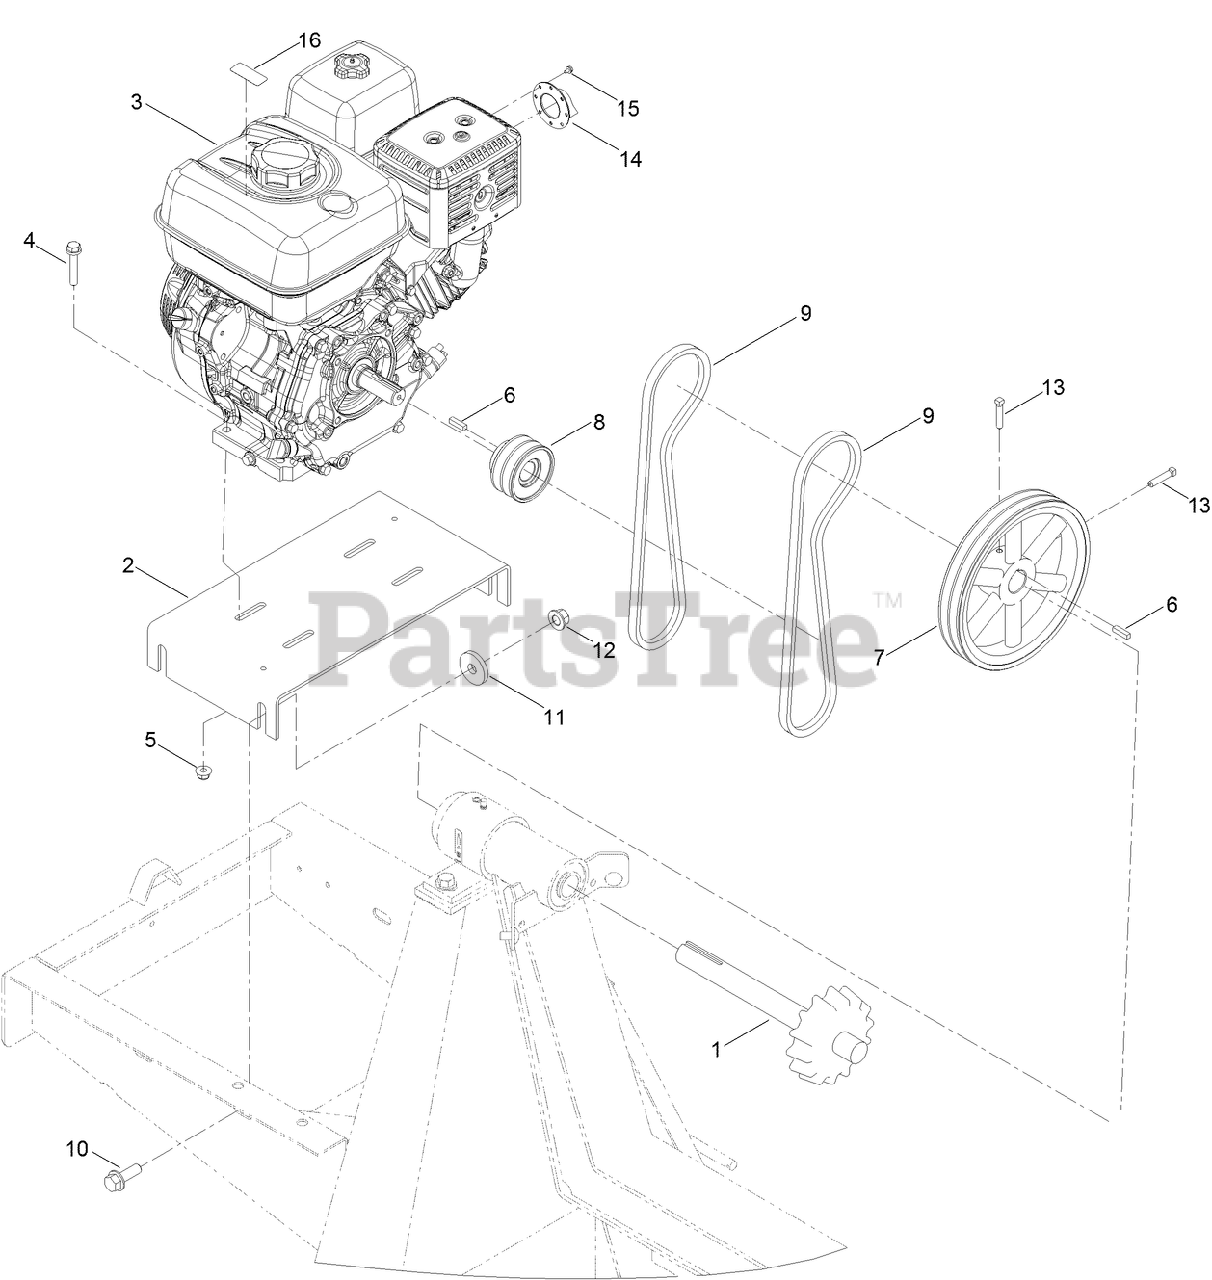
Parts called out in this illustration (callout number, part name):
1	SHAFT-DRIVE
2	BASE-ENGINE, 95CM
3	ENGINE-HONDA, GX240
4	SCREW-HHF
5	NUT-HF, NI
8	SHEAVE
9	BELT-V
10	SCREW-HHF
11	WASHER-FLAT
12	NUT-LOCK
13	SCREW-SET
14	DEFLECTOR-EXHAUST, HONDA
15	SCREW-HWH
16	DECAL-WARNING, ETHANOL
